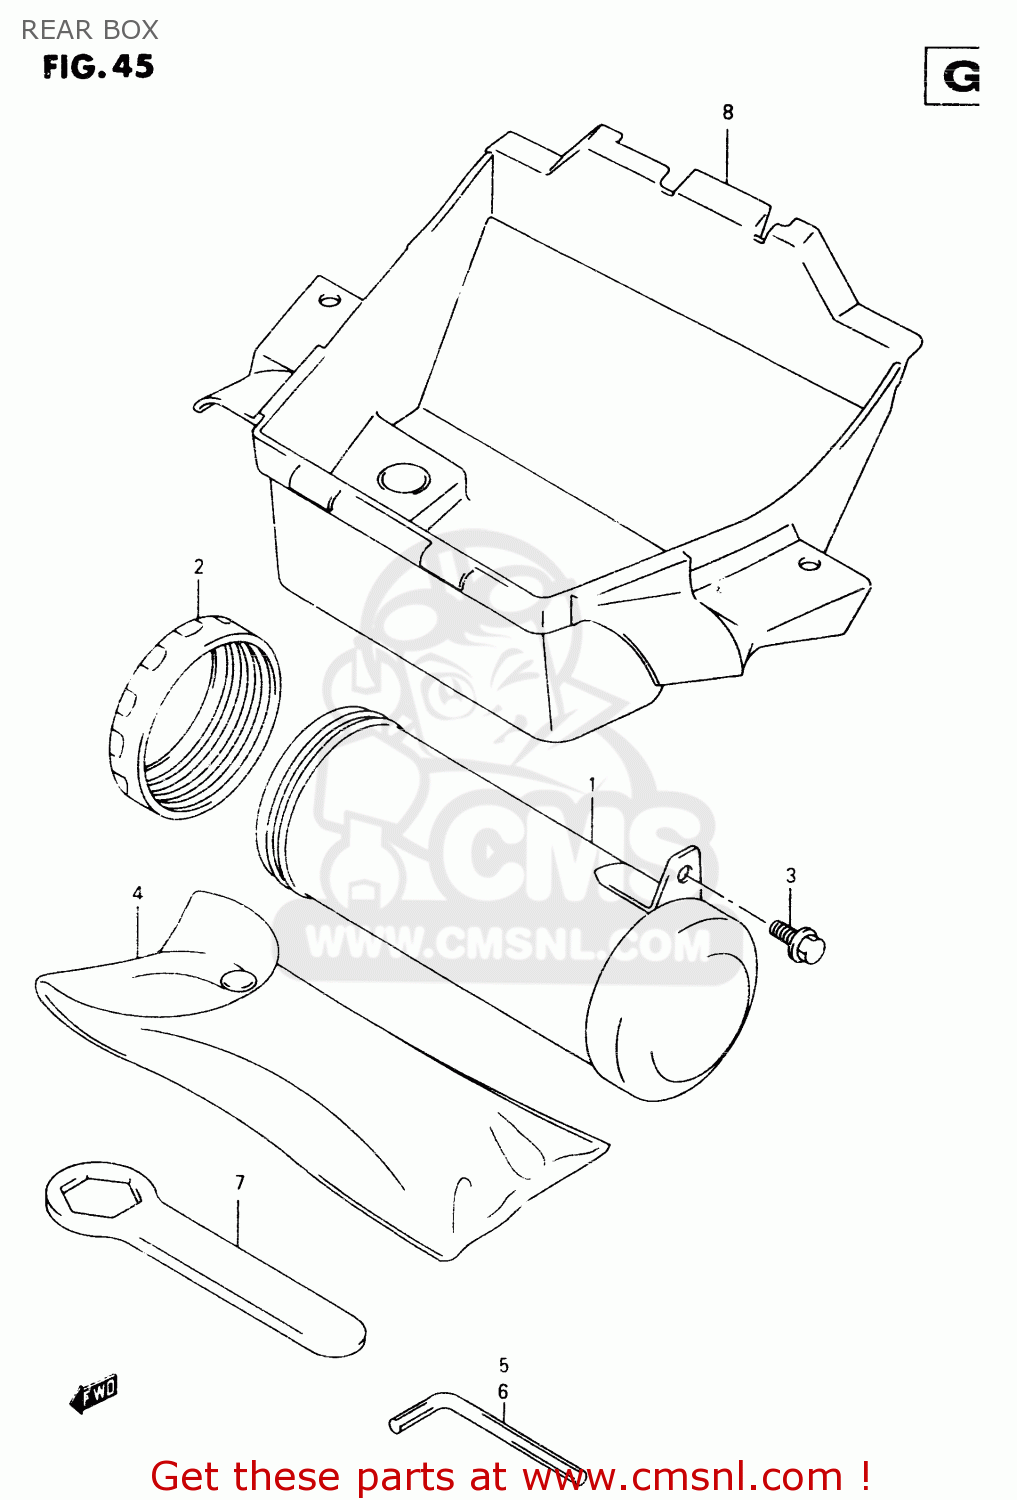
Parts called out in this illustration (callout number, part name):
1	HOLDER,TOOL
2	CAP,TOOL HOLDER
3	BOLT
4	TOOL ASSY
5	SPANNER,HEXAGON(4)
6	SPANNER,HEXAGON(6)
7	RING SPANNER(22)
8	BODY,LUGGAGE BOX
